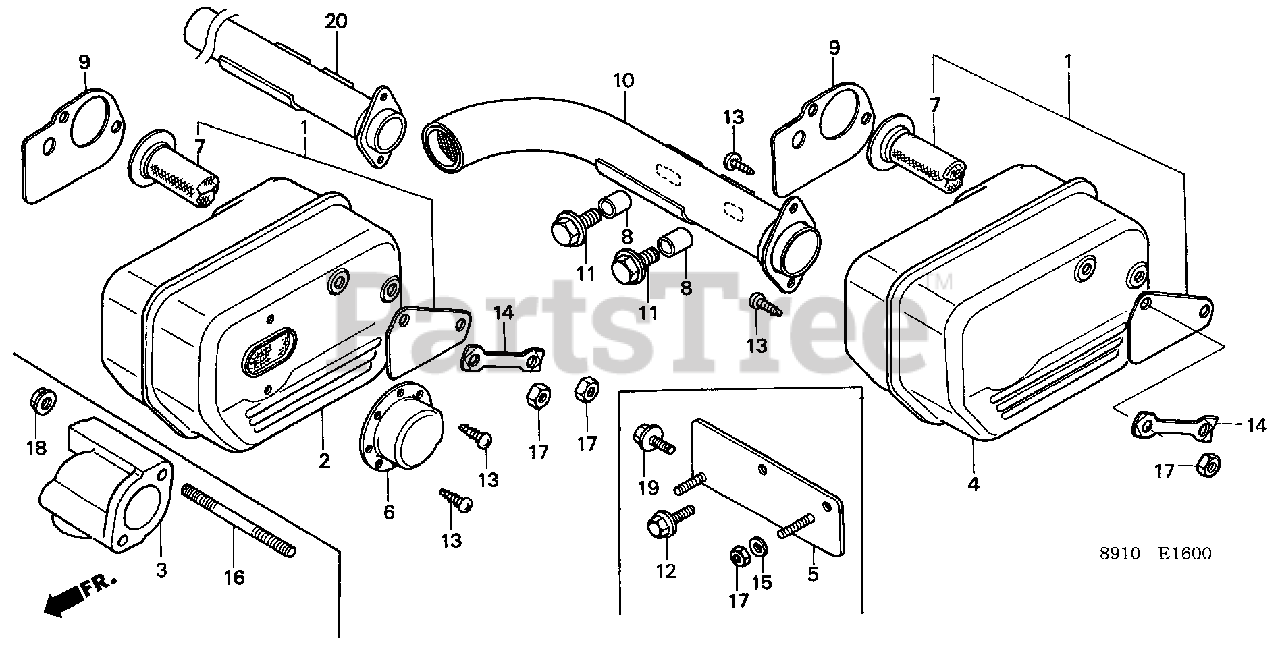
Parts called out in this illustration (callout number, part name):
1	ARRESTER KIT, SPARK
6	CAP, MUFFLER
7	ARRESTER KIT, SPARK
9	GASKET, MUFFLER (NOT AVAILABLE)
13	SCREW, TAPPING (4X8)
14	WASHER, MUFFLER (NOT AVAILABLE)
17	NUT, HEX. (8MM)
